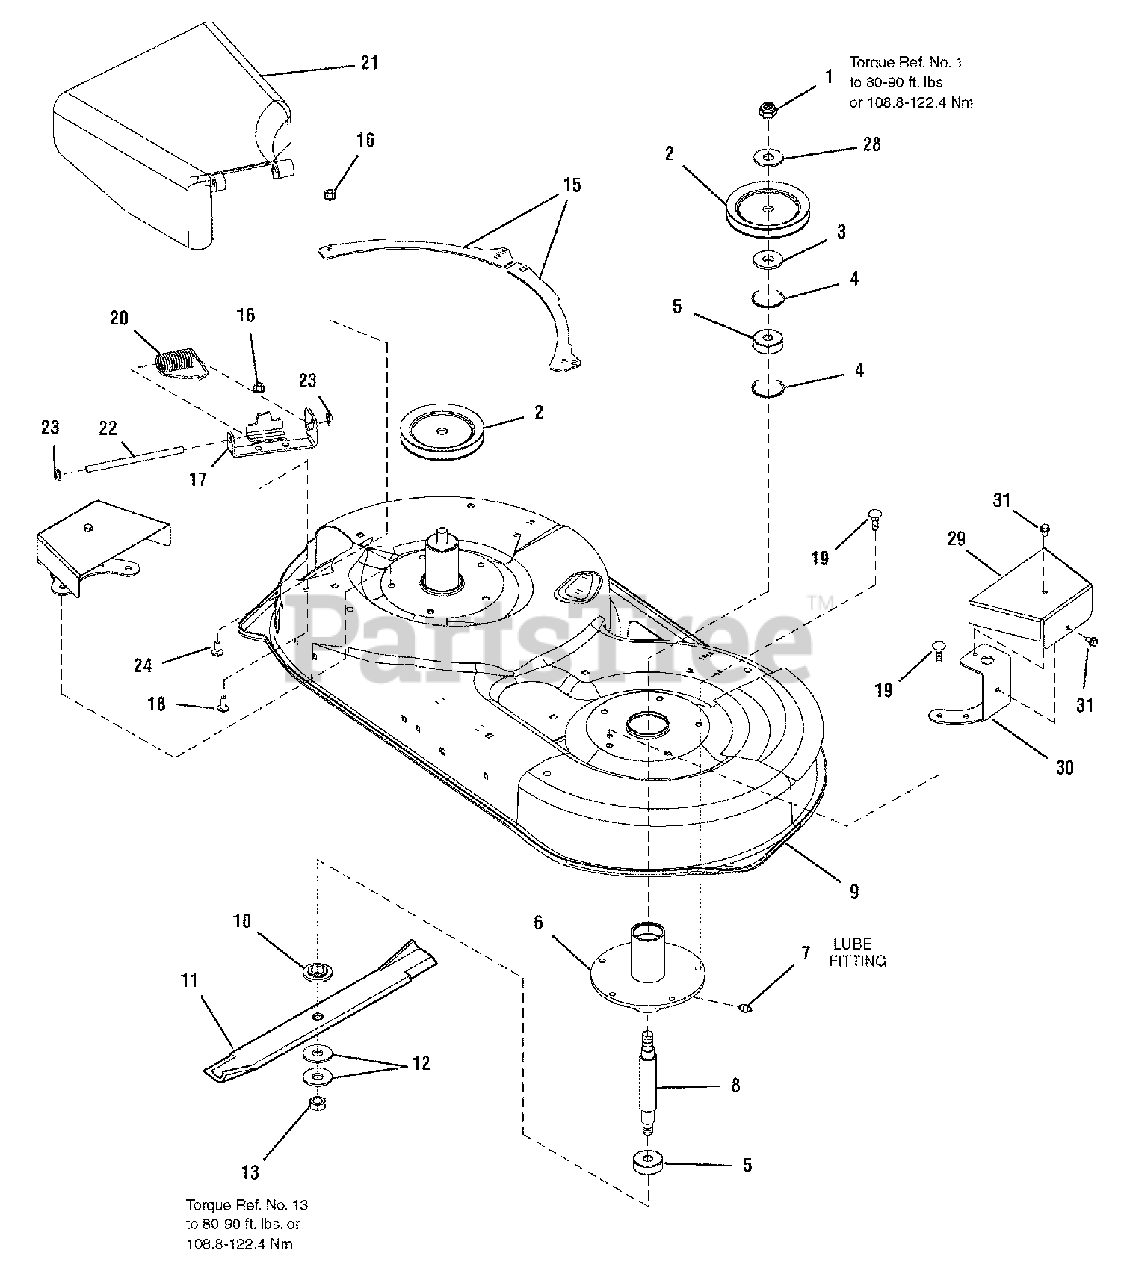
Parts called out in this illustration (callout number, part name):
1	NUT, Hex Nylock, 5/8
2	PULLEY, Drive
3	SPACER, Pulley
4	RING, Retaining
5	BEARING, Spindle, 1.78" OD, .750 ID, .610 Wide
6	TUBE & PLATE ASSEMBLY, Spindle 5.24" Tall
7	LUBE, Fitting
8	SHAFT, Spindle 7.181" Long
9	HOUSING, 42" Mower
10	WASHER, Spindle Blade
11	BLADE, 21.16" Long, .976" Hole
12	WASHER, Belleville
13	NUT, Hex, 9/16
15	PLATE, Rear
16	NUT, ESNA, 5/16
17	BRACKET, Hinge
18	BOLT, Carriage, 5/16-18 x 3/4
19	SCREW, Taptite, 3/8-16 x 3/4
20	SPRING, Torsion
21	DEFLECTOR
22	ROD, Deflector, 6.13" Long, .375" DIA
23	PUSHNUT
24	BOLT, Carriage, Short Neck, 5/16-18 x 1
28	LOCKWASHER, Internal Tooth, 5/8
29	COVER, Pulley
30	SUPPORT, Pulley Cover
31	SCREW, Taptite, 5/16 - 18 x 1/2
